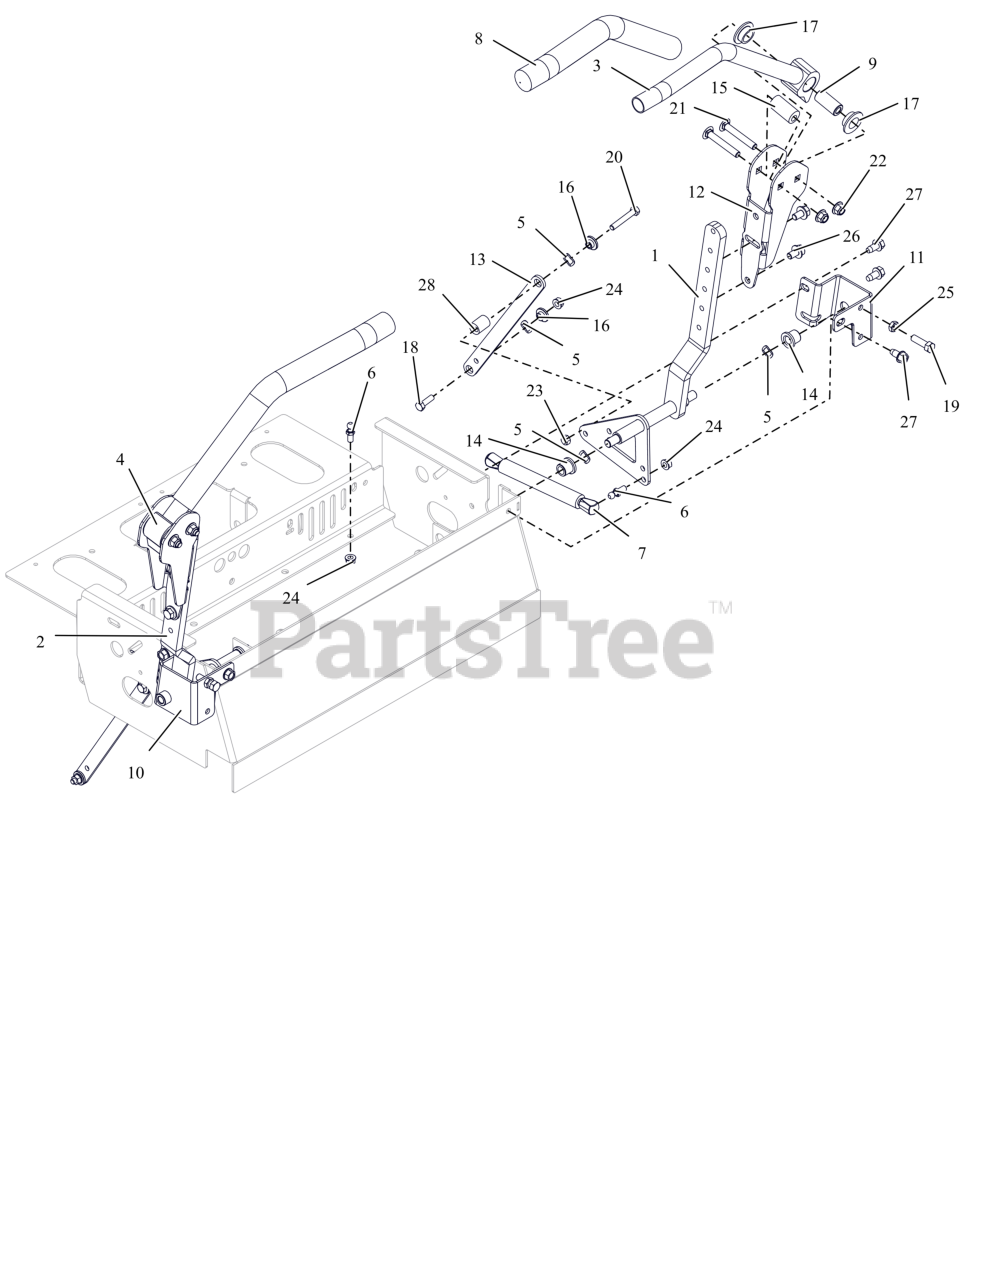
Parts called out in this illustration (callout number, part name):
1	WLDMT, LH LOWER CONTROL ARM
2	WLDMT, RH LOWER CONTROL ARM
3	WLDMT, CONTROL HANDLE-LH (BLACK)
4	WLDMT, CONTROL HANDLE-RH (BLACK)
5	WAVE WASHER .531X.781X.125FH
6	STUD- BALL
7	DAMPER
8	GRIP, HANDLEBAR
9	SPACER, STEERING ARM
10	PT200/400 RH CNTRL STP BRK-RED
11	PT200/400 LH CNTRL STP BRK-RED
12	ADJ UPPER CONTROL ARM BRKT-BLK
13	LINK, STEERING CONTROL
14	BHSG-FLG .500X.750X.750X.125
15	BSHG, ECCENTRIC.406X.875X1.625
16	BSHG-FLG .32X.500X.344X.880
17	BSHG-FLG .762X1.48X.44 NYL
18	BLT,HEX .31-18X1.00 G5 ZCC
19	BLT, HEX .38-16X1.25 G5 ZCC
20	BLT, HEX .31-18X2.00 G5 ZCC
21	BLT, RHSSN.38-16X2.50 G5 ZCC
22	NUT,NYL-FLG .38-16 GF ZCC
23	NUT,LK-CTR .31-18 GA ZCC
24	NUT-LK-TOP-FLG .312-18 GF ZCC
25	NUT-JAM .375-16 G2 ZCC
26	BLT, SERHFWH .38-16X.625 ZCC
27	SCR,TAP .375-16X.75 HWH TR ZCC
28	ECCENTRIC
